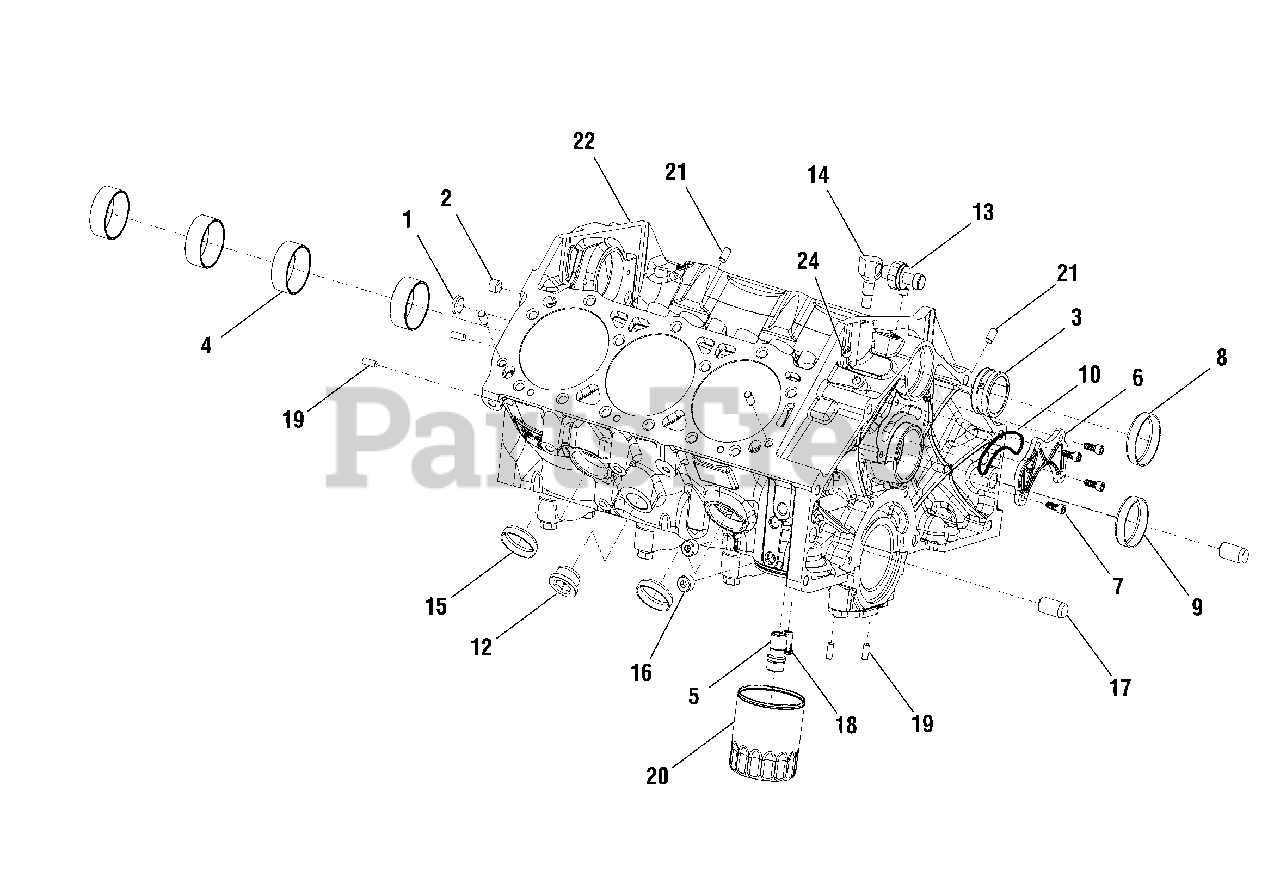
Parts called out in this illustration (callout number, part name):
1	* PLUG, CORE
2	* PLUG, CORE
3	* BEARING, BALANCER SHAFT
4	* SET, BEARING CAMSHAFT
5	* ADAPTOR, OIL FILTER
6	* COVER, REAR OIL CROSSOVER
7	* BOLT, REAR OIL CROSSOVER COVER
8	* PLUG, REAR BALANCE SHAFT
9	* PLUG, REAR CAM
10	* O-RING
12	* PLUG, COOLANT DRAIN
13	SENDER, O/PRESS
14	FITTING, OIL PRESSURE GAUGE
15	* PLUG CORE
16	* PLUG OIL GALLEY
17	* PIN, F/W HOUSING
18	* VALVE, OIL FILTER BYPASS
19	* DOWEL PIN
20	* FILTER, OIL
21	* PIN, CYLINDER HEAD
22	* CRANKCASE
24	* PLUG, OIL GALLEY
